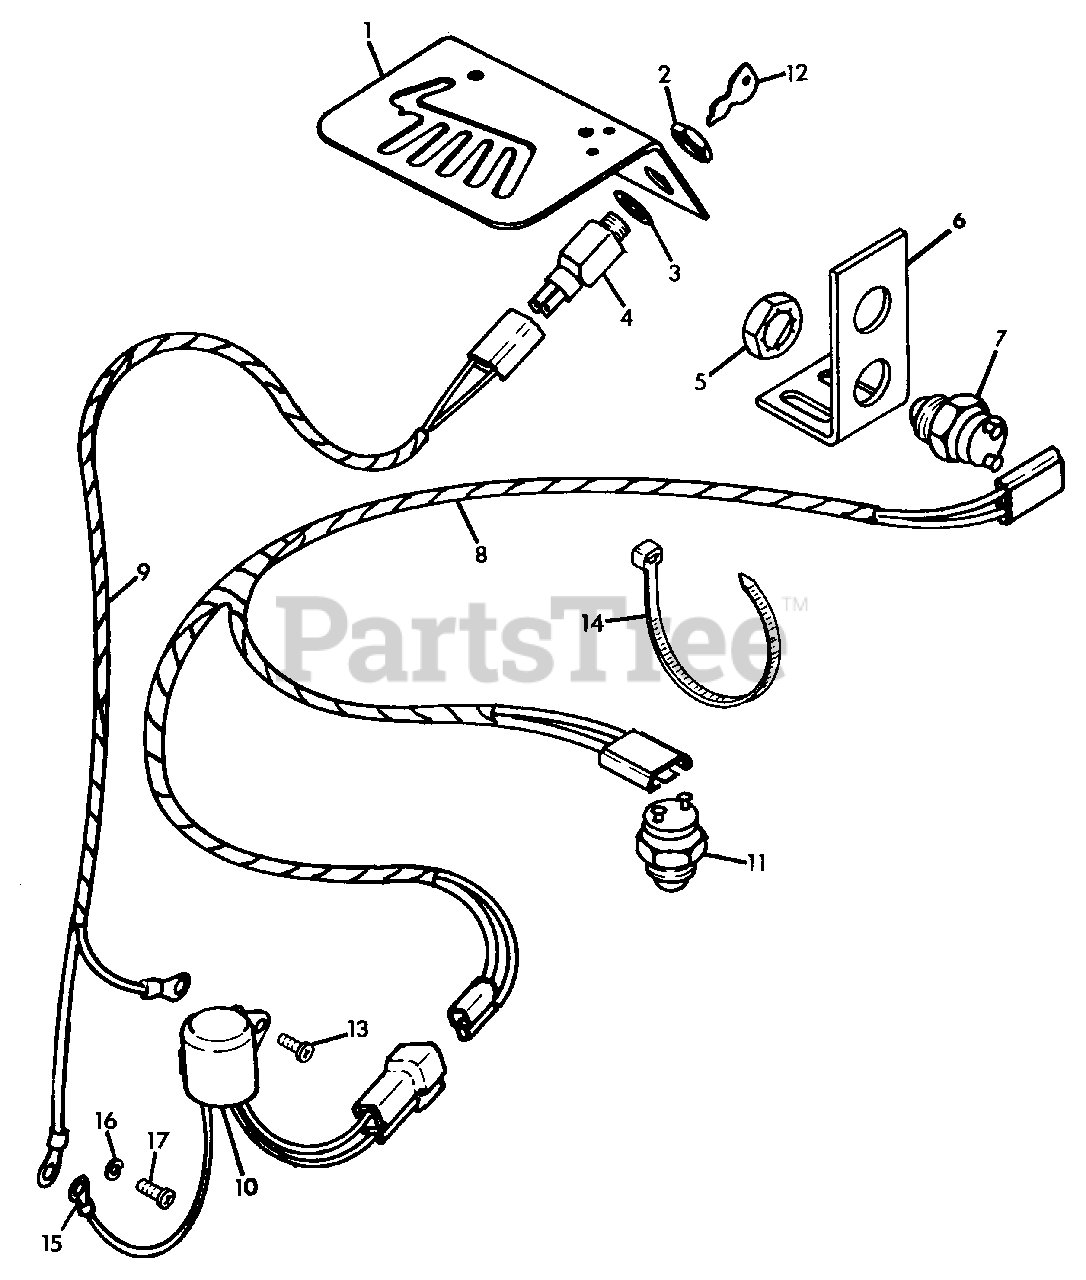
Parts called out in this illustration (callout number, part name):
1	PLATE, INSTRUCTION
2	NUT, JAM 5/8-32
3	WASHER, LOCK 5/8
4	SWITCH, KEY
5	NUT, 9/16-18
6	BRACKET, INTERLOCK SWITCH
7	SWITCH, INTERLOCK
8	HARNESS, WIRING INTERLOCK
9	HARNESS, WIRING SWITCH
10	CONTROL MODULE
11	SWITCH, NEUTRAL START
12	KEY, IGNITION SWITCH
13	SCREW, TAPPING 10-24X.50 HHD SF
14	TIE, CABLE
15	TERMINAL, CONNECTOR CLIP TYPE
16	WASHER, LOCK NO. 10
17	SCREW, MACHINE 10-32X.50 P/HD
